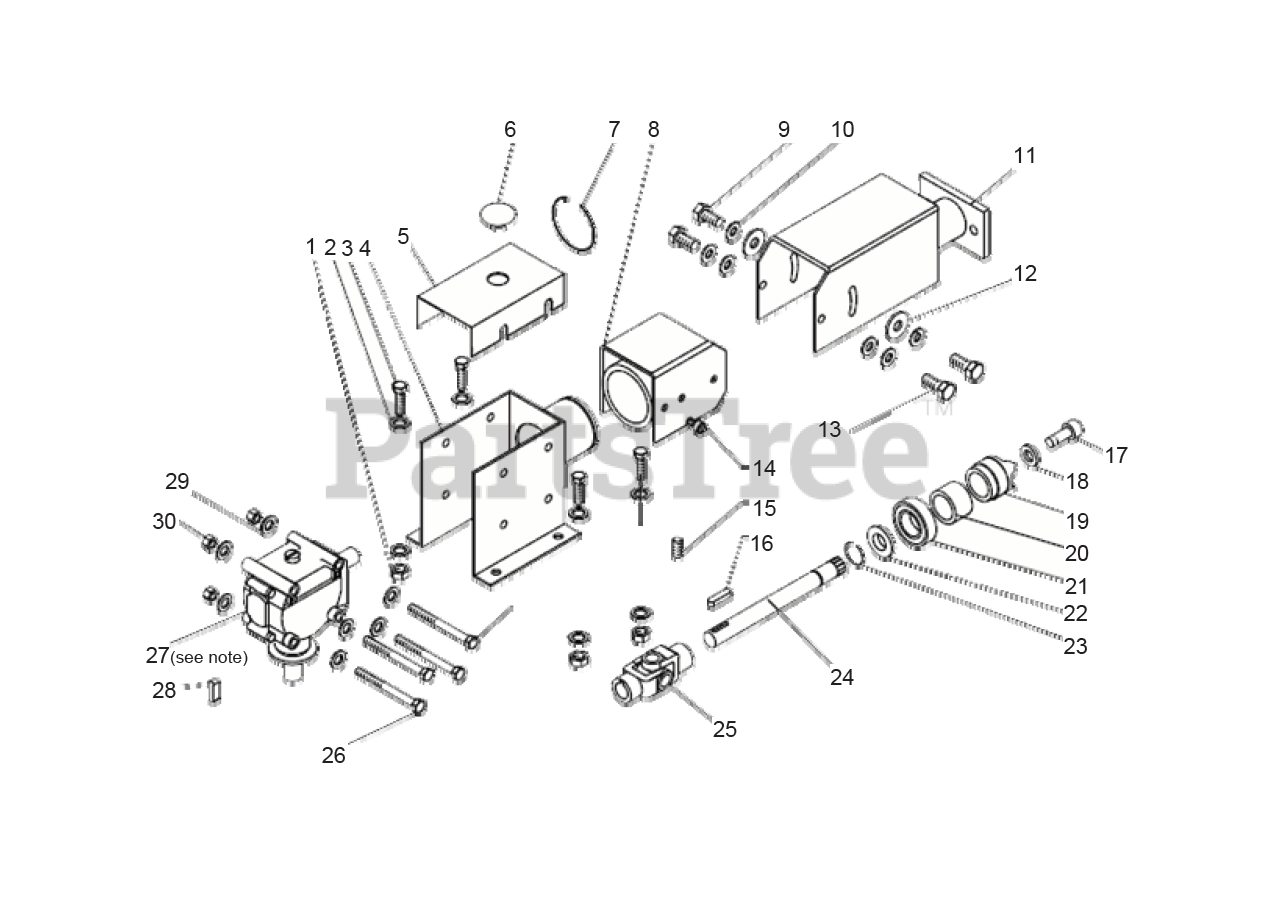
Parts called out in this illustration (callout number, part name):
2	GEAR BOX HOUSING
3	SCREW M12 12x25
4	WASHER 12 UNI6592
5	NUT M12 CONE LOCK
7	SNAP RING (SEEGER)
8	TURNING HUB FOR ARM
9	BOLT M10X25
10	WASHER SPRING
11	ARM BM21
11	ARM BM26 � BM32
12	FLAT WASHER 11-30
13	SCREW UNI 5739 M
14	10X20 Z GREASER
15	SET SCREW M10X15
16	KEY M8X7X30
17	SCREW TEC M6x20 UNI5
18	WASHER OE25 O17
19	THREE TEETH JOINT
20	SPACER
21	BEARING 6205 2 RS
22	ACER DUST LOCK
23	SNAP RING 25 UNI 7435
24	TRANSMISSION SHAFT 21�
24	TRANSMISSION SHAFT 26�/32�
25	U-JOINT NEW STYLE
26	SCREW
27	TRANSMISSION
28	KEY M8x7x35 UNI 66
29	FLAT WASHER M10
30	NUT CONELOCK M10 DIN 980
